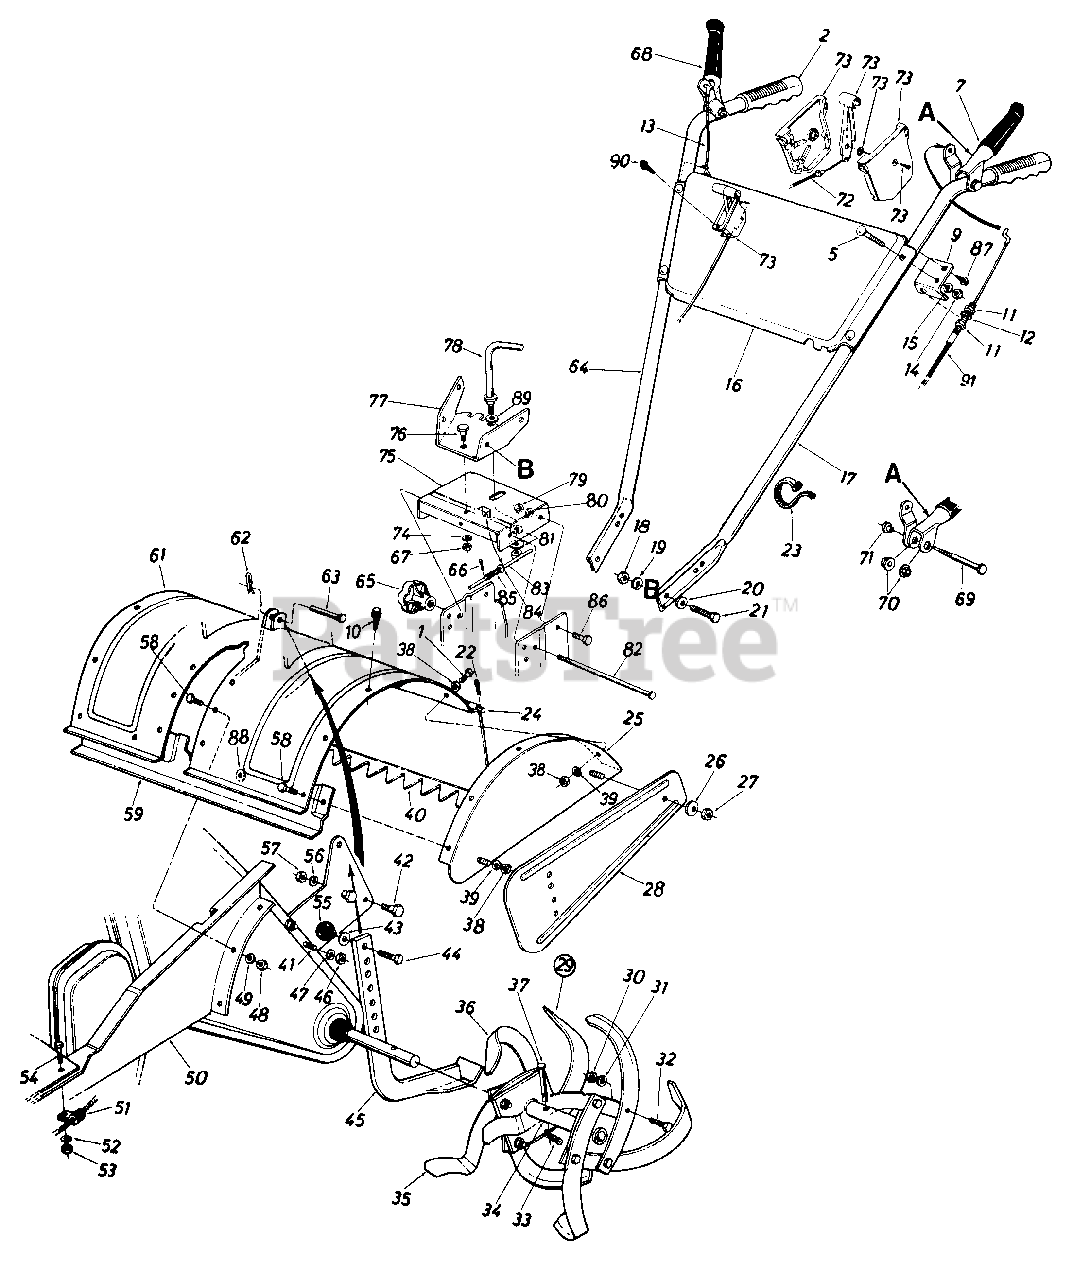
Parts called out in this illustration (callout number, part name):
1	Hex Bolt 5/16-18 x 11/4" Lg.
2	Grip
5	Carr. Bolt 5/16-18 x 1.75"
7	Clutch Grip Ass'y.-L.H. (Tines)
9	Clutch Cable Bracket
10	Hex Wash. S-Tap Scr. 5/16-18 x .62n Lg.
11	Hex Nut 5/16-24 Thd.
12	L-Wash. 5/16" I.D.
13	Wheel Drive Cable
14	Hex Nut 5/16-18 Thd.
15	L-Wash. 5/16" I.D.
16	Handle Panel
17	Handle-L.H.
18	Hex Nut 3/8-16 Thd.
19	L-Wash. 3/8" I.D.*
20	Bell-Wash. 3/8" I.D.
21	Hex Bolt 3/8-16 x 1.00" Lg.
22	Cotter Pin 3/32" Dia. x 3/4"
23	Cable Tie
24	Tiller Flap Rod
27	Hex Nut 5/16-18 Thd.
31	L-Wash. 3/8" I.D.
32	Hex Bolt 3/8-24 x 1.25" Lg.
33	Hairpin Cotter
38	Hex Nut 5/16-18 Thd.
39	L-Wash. 5/16" I.D.
41	Hex Bolt 5/16-18 x 1.0" Lg.
42	Shld. Bolt 1/2" Dia. x .426"
43	Fl-Wash. 3/8" I.D. x 5/8" O.D.
44	Hex Bolt 3/8-16 x 3/4" Lg.
46	Hex Nut 5/16-18 Thd.
47	L-Wash. 5/16" I.D.
48	Hex Nut 5/16-18 Thd.
49	L-Wash. 5/16" I.D.
52	L-Wash. 5/16" I.D.
53	Hex Nut 5/16-18 Thd.
54	Hex Bolt 5/16-18 x 3/4" Lg.
55	Ball Knob 1-1/4" Dia.
56	L-Wash. 3/8" I.D.
57	Hex Nut 3/8-16 Thd.
58	Hex Bolt 5/16-18 x .75" Lg.
63	Clevis Pin 3/8" Dia.
64	Handle-R.H.
65	Hand Knob
66	Cotter Pin 1/16" Dia. x .75" Lg.
67	Hex Cent. L-Nut 3/8-16 Thd.
68	Clutch Grip Ass'y.-R.H.
69	Shoulder Bolt .88n Dia. x 1.53" Lg.
70	Hex Flange Plastic Bearing
71	Shoulder Nut 1/4-20 Thd.
72	Throttle Control Wire
73	Throttle Control Box Ass'y.
74	Bell-Wash..40" I.D.
79	Hex Cent. L-Nut 3/8-16 Thd.
80	Bell-Wash. .40" I.D. x .88" O.D.
81	Bell-Wash. 1/2" I.D. x 1.00" O.D.
82	Lock Pin 5/16n Dia. x 8"
83	Lower Sliding Ass'y.
84	Fl-Wash. .291" I.D. x .62" O.D.
85	Compression Spring .36" O.D. x l.Oon Lg.
86	Shoulder Bolt 1/2n Dia. x .170" Lg.
87	Hex Wash. S-Tap Scr. 1/4-20 x.50" Lg.
88	Bell-Wash. 5/16" I.D.
89	Fl-Wash. 5/8" I.D.
90	Self-Tap Scr. #10 x 1/2" Lg.
91	Tine Control Cable
